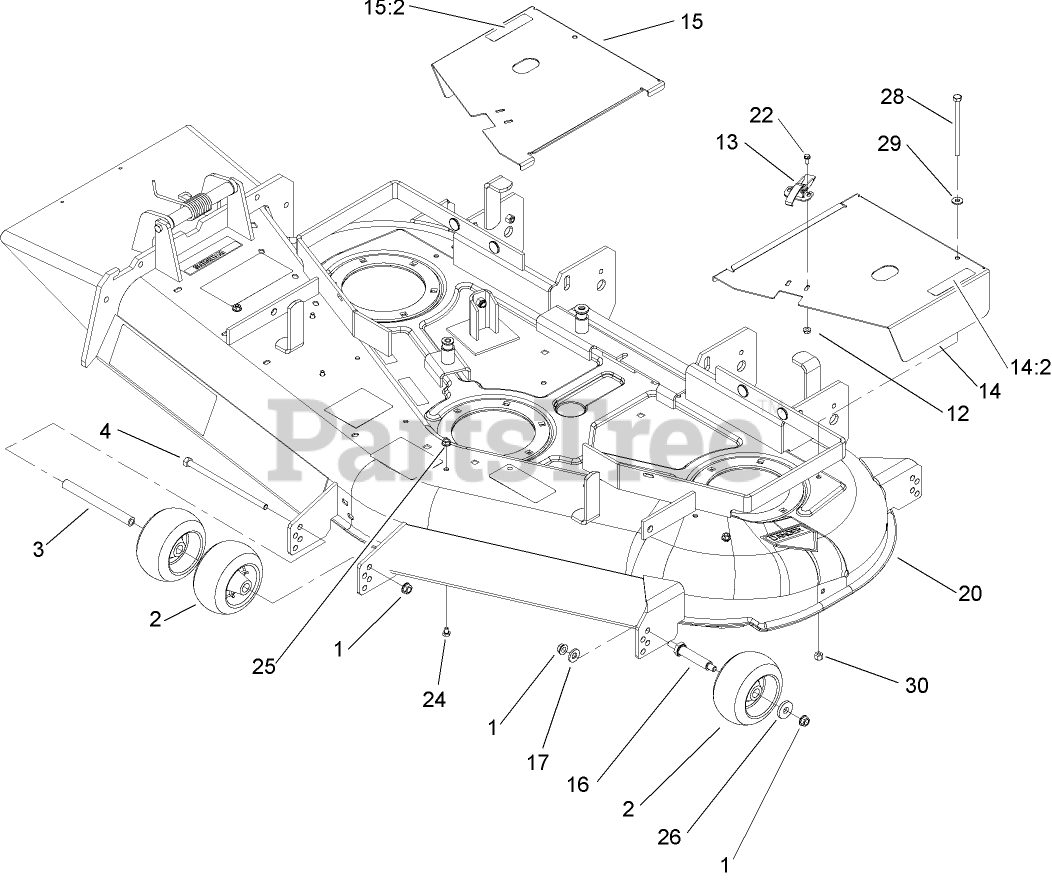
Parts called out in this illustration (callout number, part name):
1	NUT-HHF, WHIZ
2	WHEEL-GAGE
3	SPACER-WHEEL
4	SCREW-HH
12	NUT-LOCK, FLANGE
13	CLAMP-SLOTTED
14	LH COVER ASM
14:2	DECAL-WARNING
15	RH COVER ASM
15:2	DECAL-WARNING
16	SPACER
17	WASHER-BELLEVILLE
20	DECK AND DEFLECTOR ASM
22	SCREW-HWH
24	SCREW-HH
25	NUT-HF
26	WASHER
28	SCREW-HH
29	WASHER-FLAT
30	NUT-LOCK, NI
